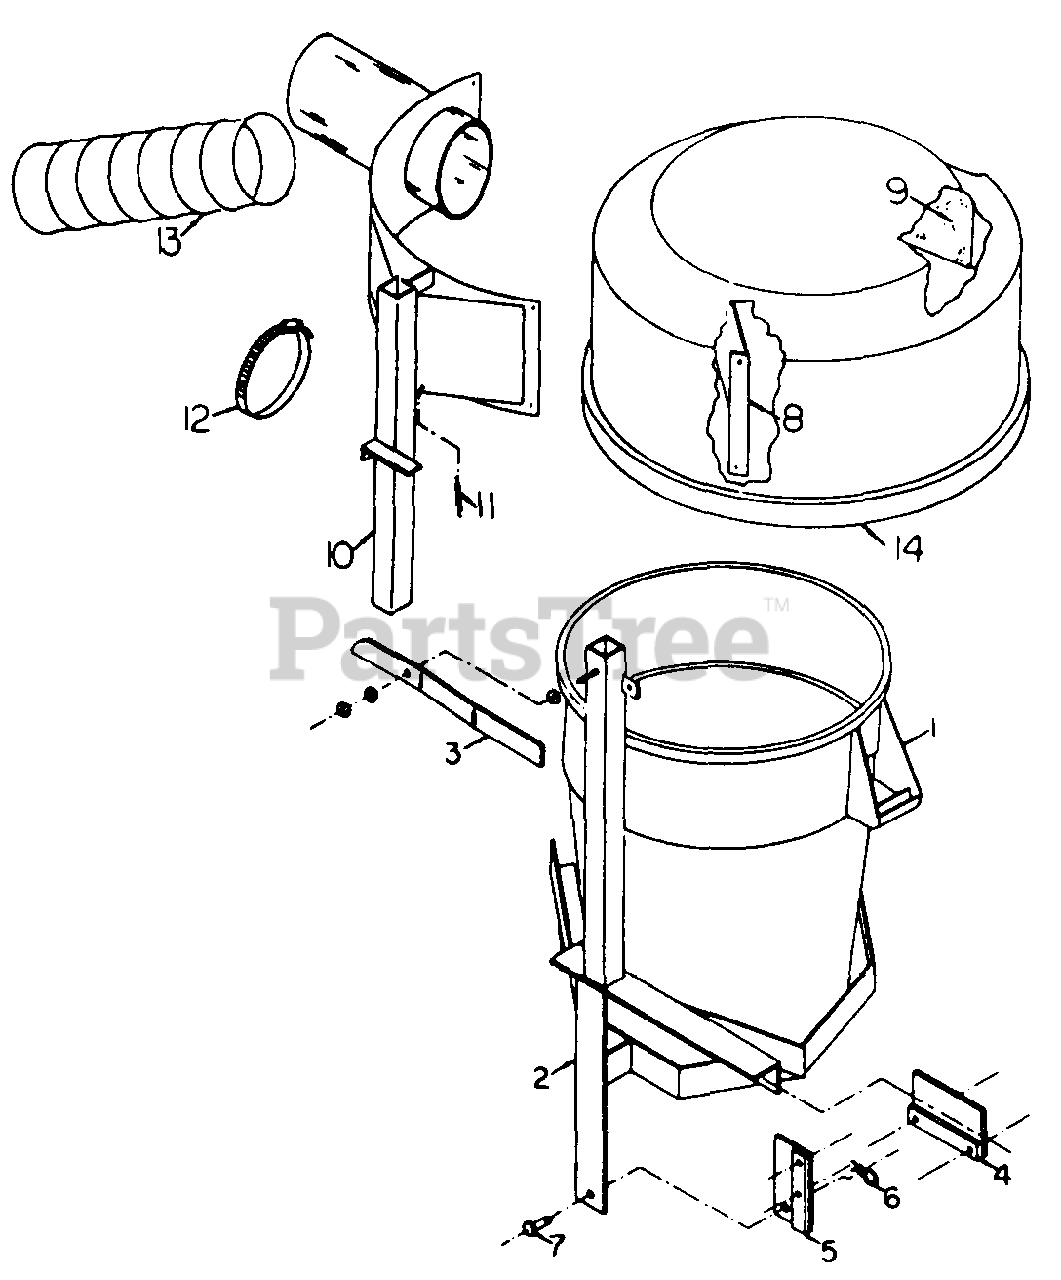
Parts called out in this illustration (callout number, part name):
3	Handle
4	Top Mount
6	Hair Pin Cotter, .120 x 2 1/2"
7	Clevis Pin, 1/2" x 1 1/2"
10	Barrel Lid Mount
13	Hose
